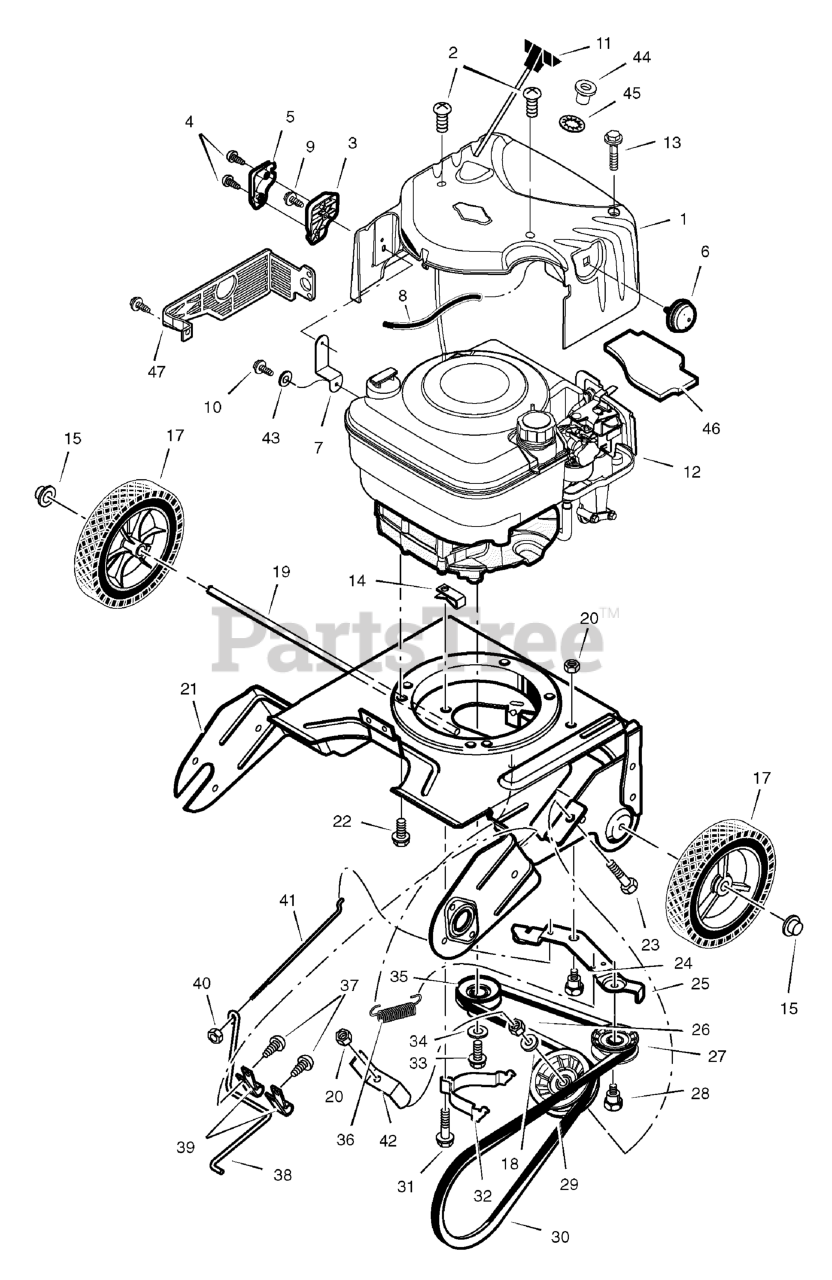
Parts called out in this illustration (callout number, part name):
1	Cover, Top
3	Base, Chute Rod
5	Cover, Chute Rod
6	Primerbulb, Red
7	Bracket, Engine Chute
11	Handle, Starter
12	Engine
14	Retainer
15	Nut, Push Cap
17	Wheel & Tire
18	WASHER, Flat, 13/32
21	Frame, Motor Box
23	Bolt
24	Bolt, Shoulder
25	Bracket, Idler Arm
26	Nut
27	Pulley, V-Belt
28	Bolt, Shoulder
29	Pulley, Flat Idler
32	Guide, Belt
33	Screw
34	Washer
38	Arm, Brake
40	Nut
41	Rod, Adjustment
42	Guide, Belt
43	Lockwasher
44	Guide, Rope
45	Spring Grip Washer
46	Seal, Foam
47	Guard, Muffler
